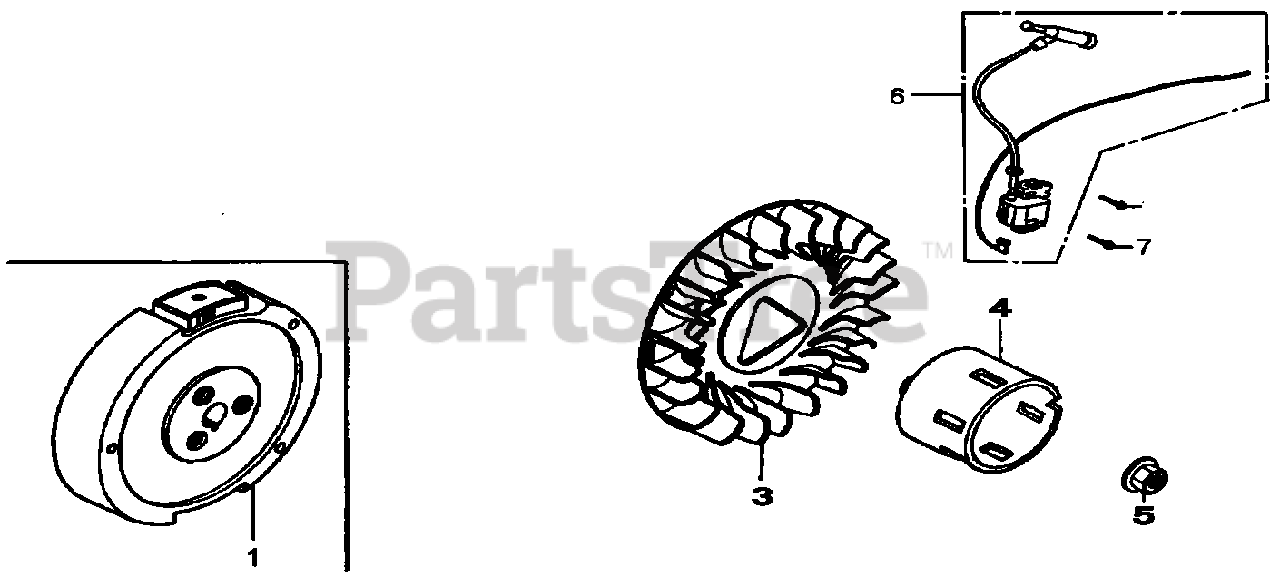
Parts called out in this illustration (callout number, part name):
3	FAN COOLING
4	PULLEY, STARTER
5	NUT SPECIAL, M16
6	COIL ASSY., IGNITION
7	BOLT, FLANGE
